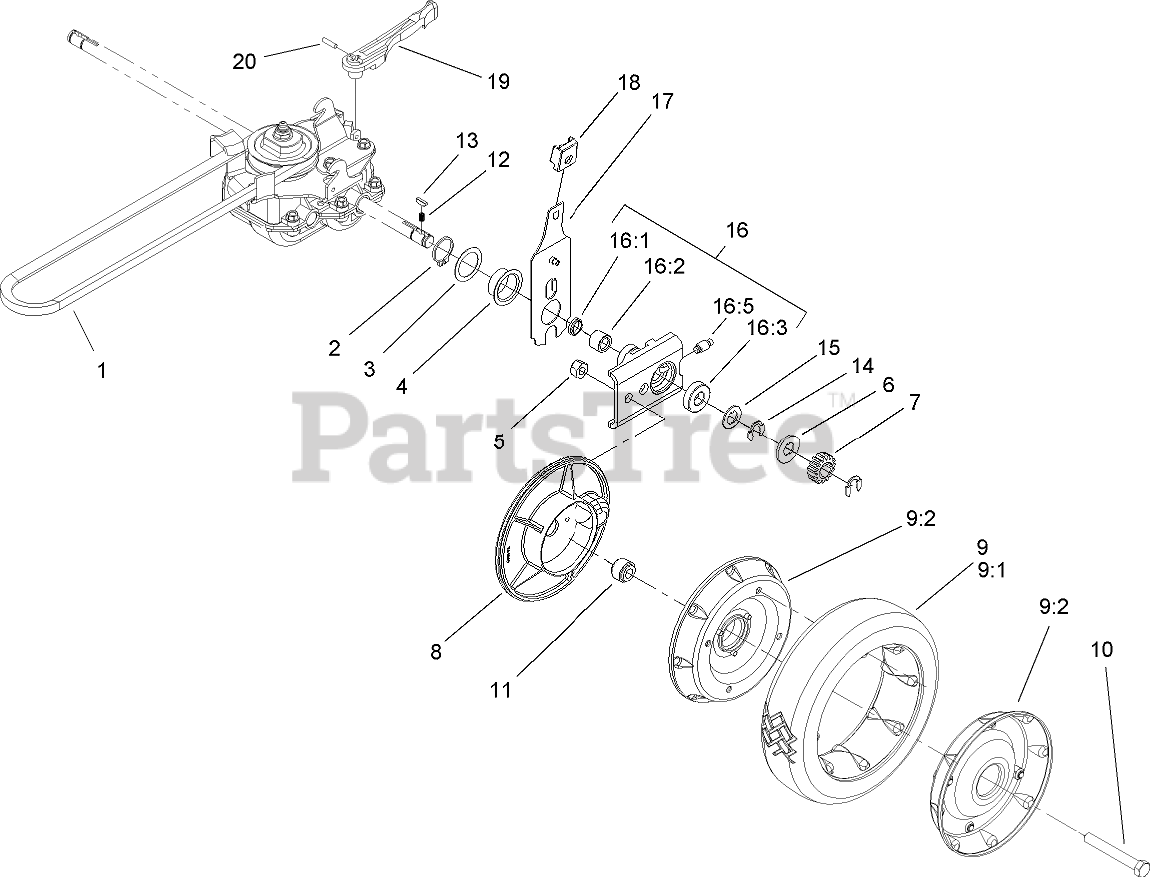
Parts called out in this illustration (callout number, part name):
1	V-BELT
2	RING-RETAINING
3	WASHER
4	CAP-END
5	NUT-LOCK, CONE
6	WASHER-THRUST, OUTER
7	GEAR-PINION
8	COVER-WHEEL
9	Wheel And Tire ASM
9:2	Wheel ASM
10	SCREW-HH
11	SPACER-COVER, WHEEL
12	SPRING-COMPRESSION
14	RING-RETAINING
15	WASHER-THRUST, OUTER
16	PIVOT ARM ASM
16:1	SEAL-OIL
16:2	BEARING-ROLLER
16:3	BEARING-WHEEL
17	REAR SPRING ARM ASM
18	KNOB-ARM
19	LEVER-SHIFT
20	PIN-COIL
99	GRASS BAG ASM
